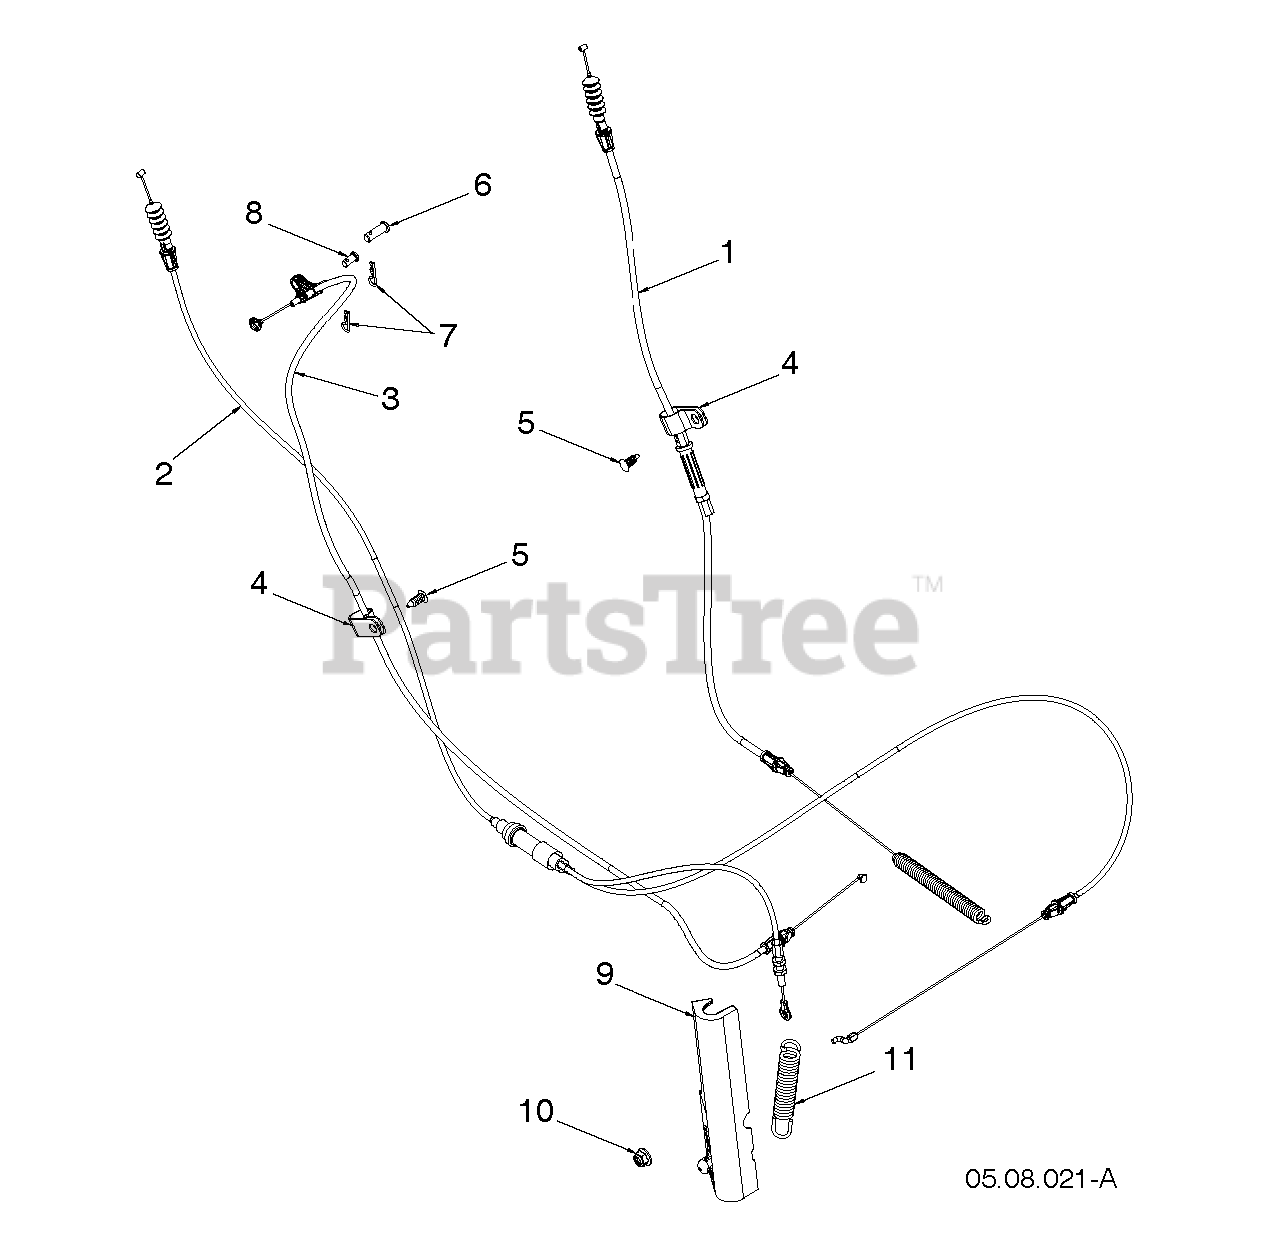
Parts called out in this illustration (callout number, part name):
1	Cables
2	CABLE IMPELLER
3	Cables
4	CLIP.CABLE.BLK
5	FASTENER.PUSH.O.250X0.783
6	PIN CLEVIS 5/16X.875
7	HAIRPIN.SOFT.ZINC.059X1.125
8	PIN CLEVIS .25 X .31
9	COVER AUGER CABLE
10	NUT HEXAGON FLANGE 5/16-18 ST
11	SPRING EXTENSION; AUGER EXTENS
